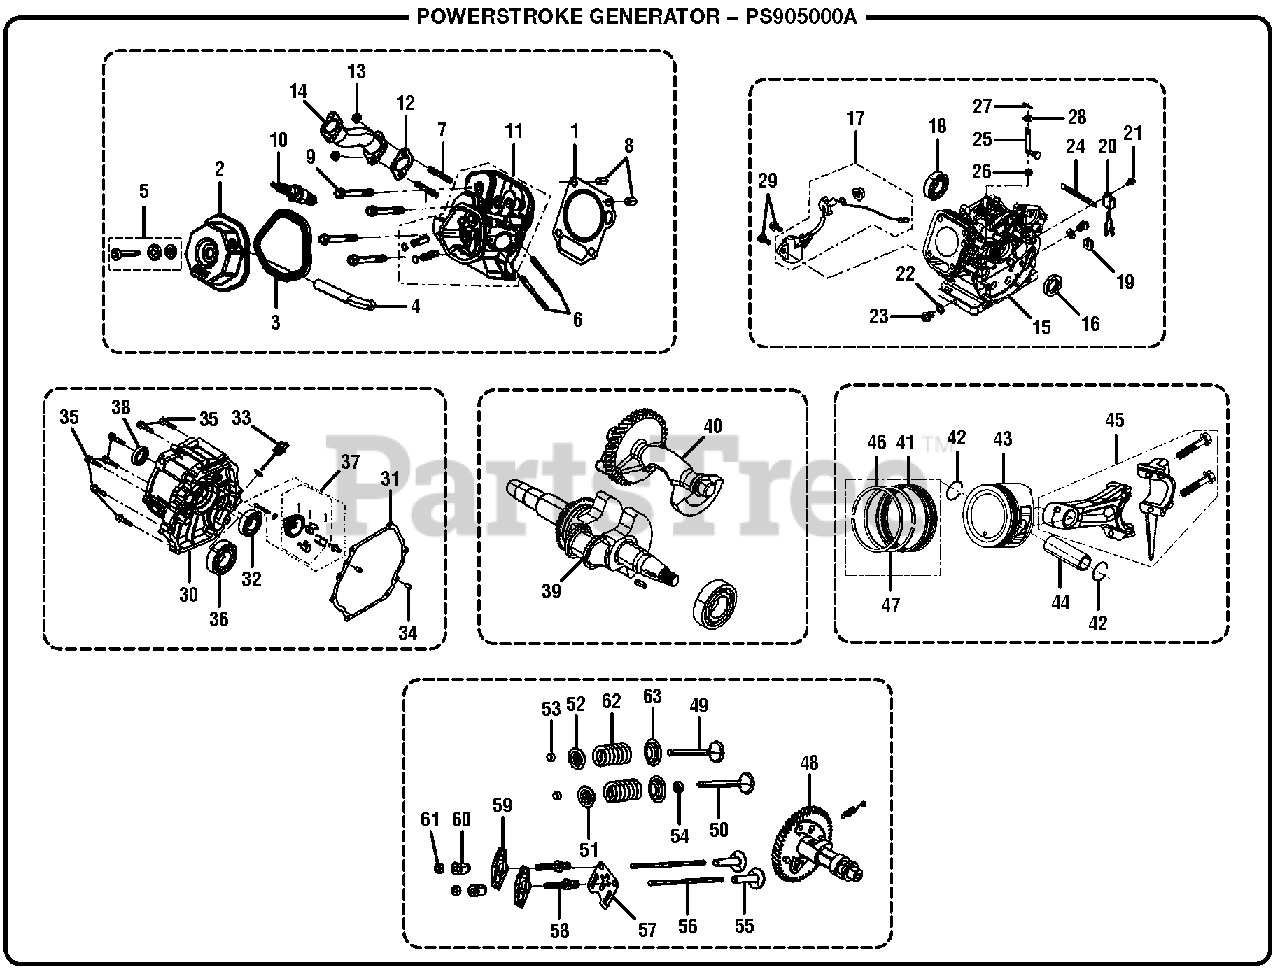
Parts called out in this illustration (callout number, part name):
1	Cylinder Head Gasket
2	Cylinder Head Cover
3	Cylinder Head Cover Gasket
4	Breather Tube
6	Threaded Stud
7	Threaded Stud
10	Spark Plug
11	Cylinder Head Assembly
12	Exhaust Outlet Gasket
14	Exhaust Pipe
15	Crankcase Assembly
17	Engine Oil Sensor
18	Ball Bearing
20	Oil Protector
25	Governor Arm
27	Pin
30	Crankcase Cover
31	Crankcase Gasket
32	Ball Bearing
33	Oil Dipstick Assembly
36	Ball Bearing
37	Governor Gear Assembly
39	Crankshaft Assembly
40	Balancing Shaft
41	Oil Ring Kit
42	Piston Pin Clip
45	Connecting Rod
46	The First Ring
47	The Second Ring
48	Camshaft Assembly
49	Exhaust Valve
50	Intake Valve
51	Valve Spring Seat
52	Exhaust Valve Retainer
53	Valve Rotator
56	Valve Lifter Assembly
57	Stop Plate Assembly
58	Valve Adjusting Bolt
59	Valve Rocker
60	Valve Adjusting Nut
61	Valve Lock Nut
62	Valve Spring
63	Valve Spring Retainer
